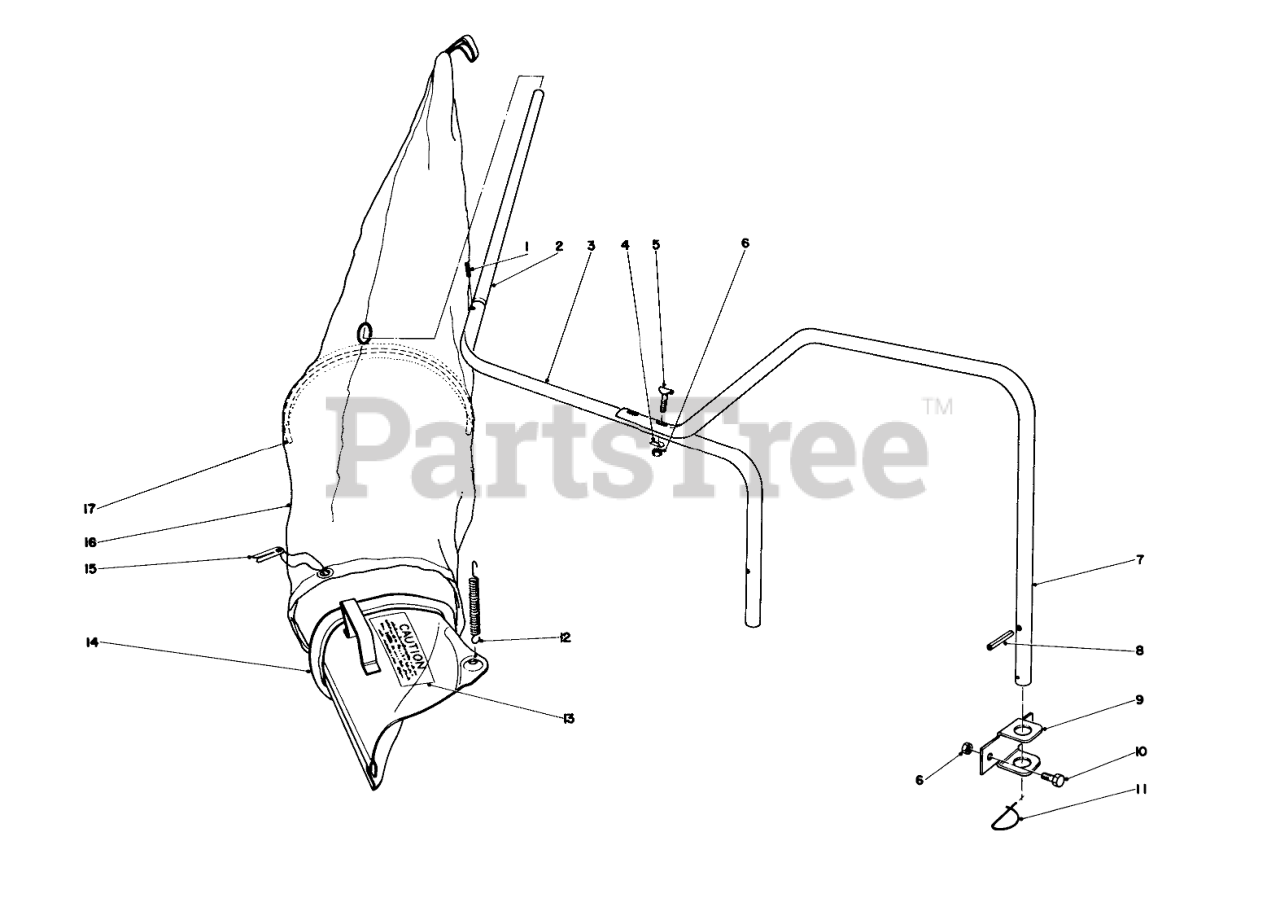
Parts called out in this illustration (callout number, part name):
1	PIN-ROLL
2	Upper Bag Arm
3	Lower Bag Arm
4	Curved Washer
5	1-1/4 LG HANDLE SCREW
6	NUT-LOCK, CONE
7	Bag Arm Support
8	PIN-ROLL, SLOTTED
9	Support Bracket
10	SCREW-HH
11	PIN-LYNCH
12	Spring
13	Decal
14	Bag Chute (Incl. Ref. No-s. 12 & 13)
15	BAG CORD FASTENER
16	Bag Assembly (Incl. Ref. No. 15)
